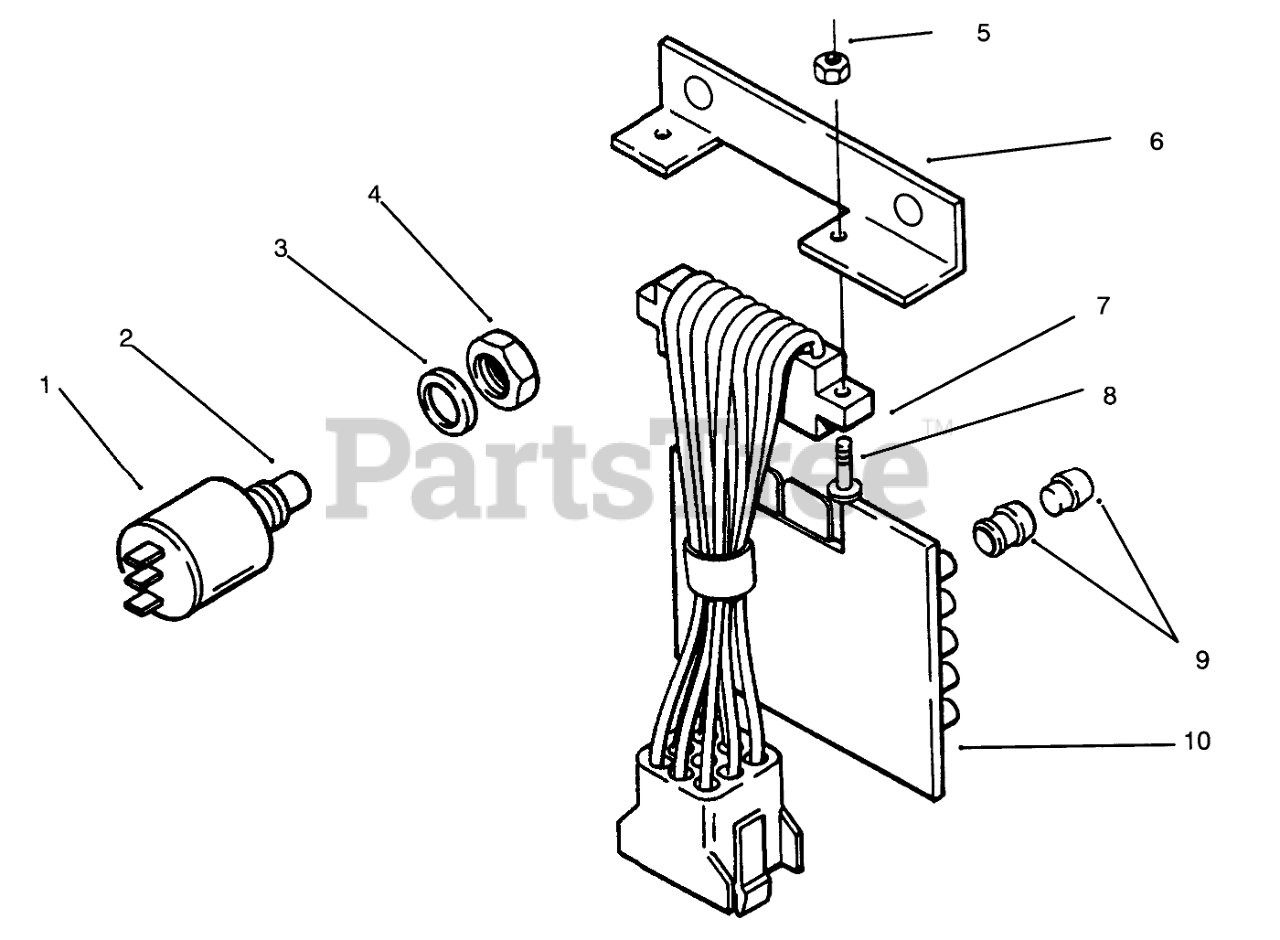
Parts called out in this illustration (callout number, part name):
1	SWITCH-PUSH BUTTON
2	Switch-Button (Incl. Ref. #2-4)
3	Washer
4	NUT F/W 116796
5	NUT HEX 4-40 ELAST
6	BRACKET
7	P.C.-BOARD HARNESS
8	Screw
9	ASSY LENS & BUSHING
10	Board-Pc
